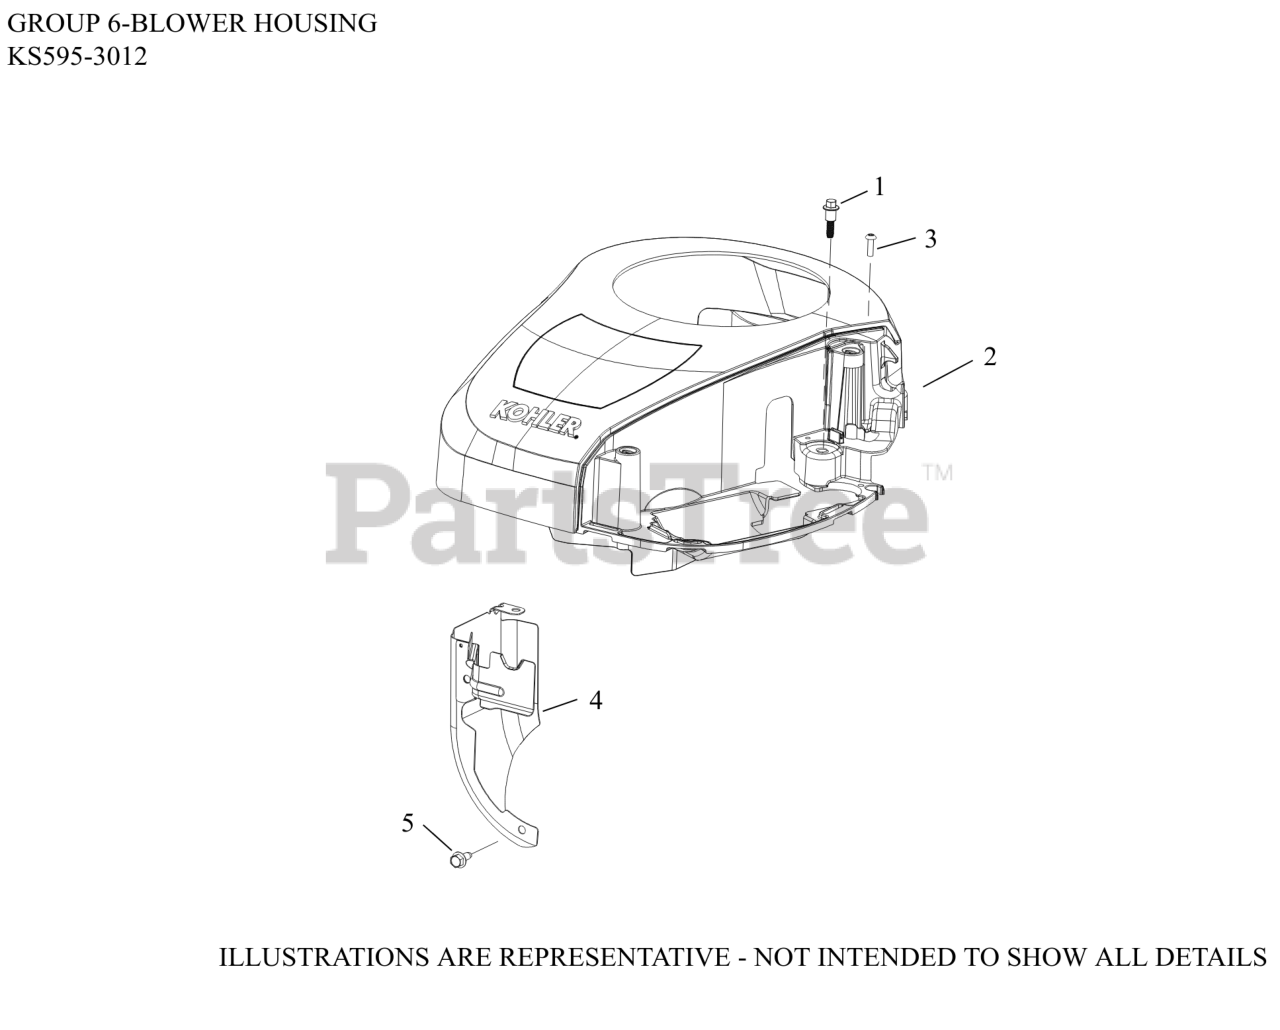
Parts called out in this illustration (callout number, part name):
1	SCREW, SHD THD FRM M6X1X26
2	KIT, BLOWER HOUSING
3	SCREW, HI-LOW
4	BAFFLE, BARREL ASSY
5	SCREW, THREAD FORMING
